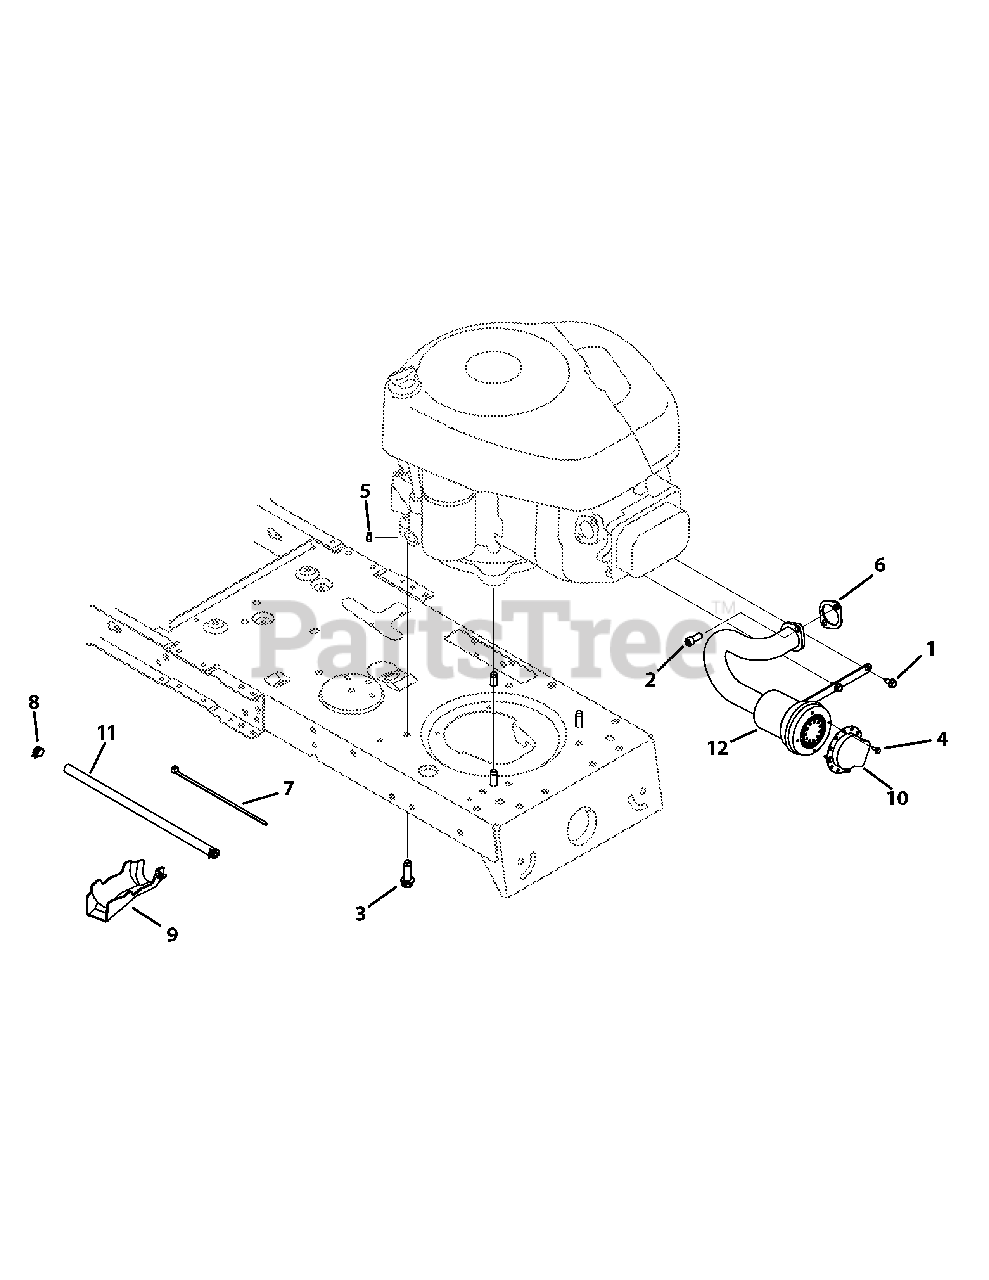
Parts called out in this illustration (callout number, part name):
1	Hex Wash S-Tapp Screw 1/4-20 x .50
2	Socket HD Cap Screw. 5/16-18 x .75
3	Hex Wash S-Tapp Screw 3/8-16 x 1.0
4	Hex Wash HD AB S-Tapp Screw #8-.50
5	Sems Nut 1/4-20
6	Exhaust Gasket
7	Cable Tie
8	Hose Clamp
9	Oil Drain Sleeve
10	Muffler Deflector
11	Fuel Line
12	Muffler, Bug
